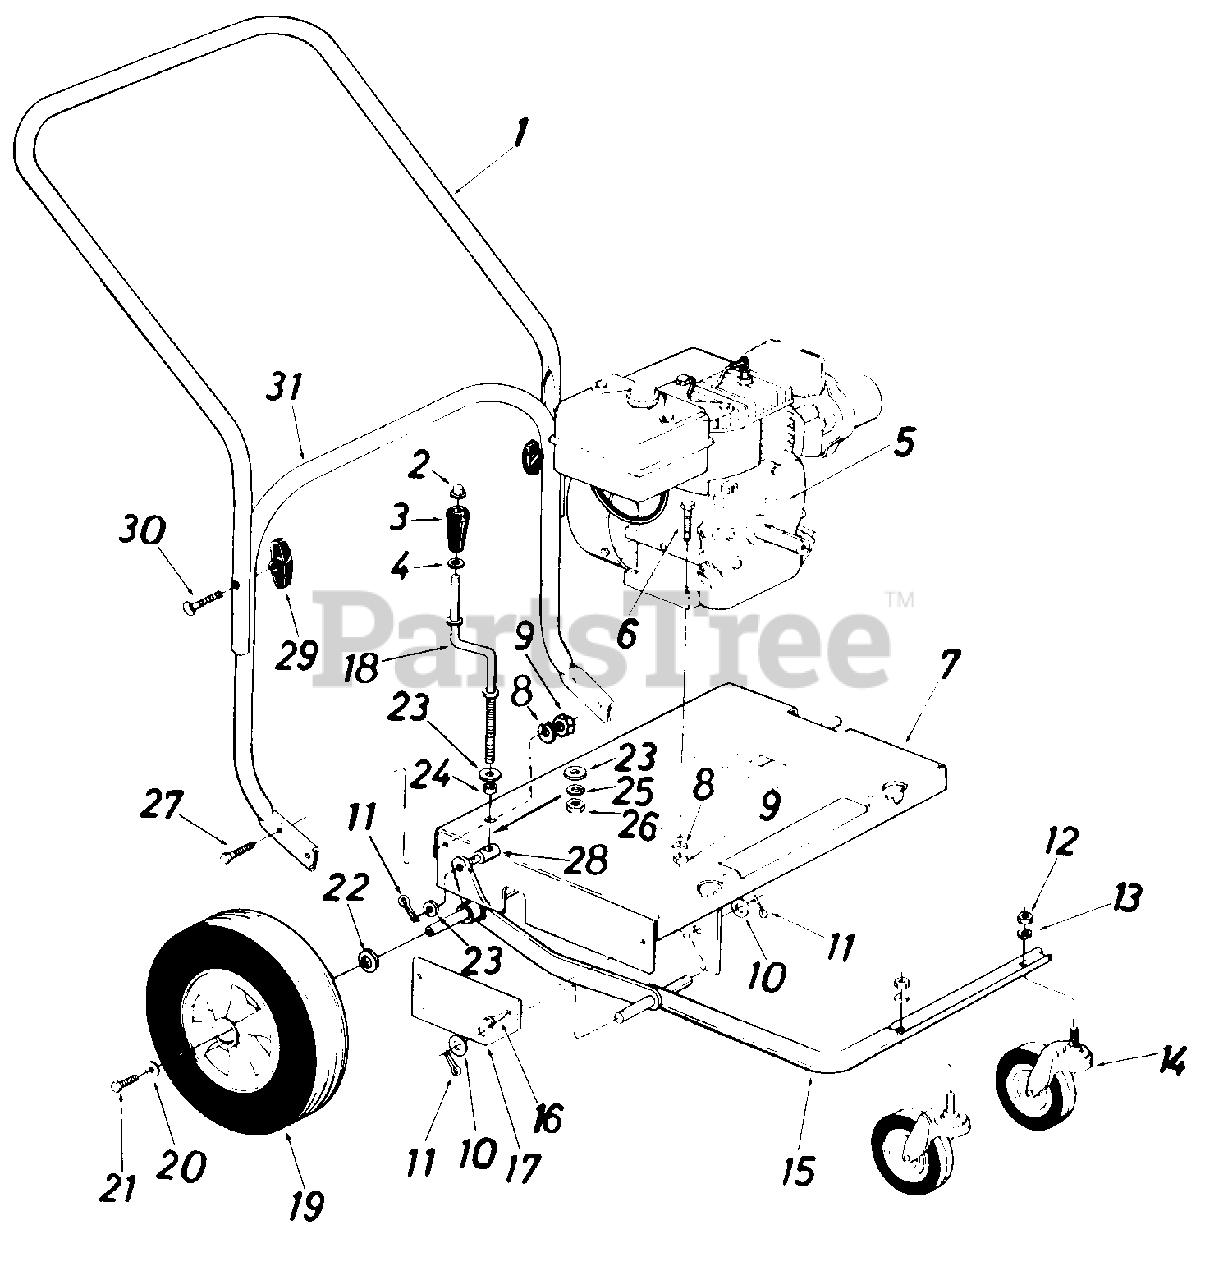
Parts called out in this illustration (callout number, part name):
1	Upper Handle
2	Push Nut 3/8" Rod
3	Crank Knob
4	Fl.-Wash. .385" I.D. x .62" O.D.
5	Sq. Key 1/4" x 2.0" Lg.
6	Hex Bolt 5/16-18 x 1.50" Lg.
7	Engine Mounting Fram Ass'y.
8	L.-Wash.5/16" I.D.
9	Hex Nut 5/16-18 Thd.
10	Fl.-Wash. .63" I.D. x 1.25" 0. D.
11	Cotter Pin 1/8" Dia. x 1.0" Lg.
12	Hex Nut 1 /2-13 Thd.
13	L.-Wash. 1/2 " I.D.
14	Swivel Caster Wheel 5" Dia. x 1.25"
19	Wheel Ass'y. Comp. 12" x 3" (Plastic)
20	Fl.-Wash. 34" I.D. x .87" O.D.
21	Hex Locking Bolt 5/16-24 x.62" Lg.
22	Fl.-Wash.
23	Fl.-Wash. .38" I.D. x .57" O.D.
24	Spacer .382" I.D. x .50" O.D. x .180" Lg.
25	L.-Wash. 3/8" I.D.
26	Hex Nut 3/8-16 Thd.
27	Hex BoIt 5/16-18 x .75 " Lg.
28	Ferrule
29	Hand Knob
30	Carriage Bolt 5/16-18 x 2.0" Lg.
31	Lower Handle
